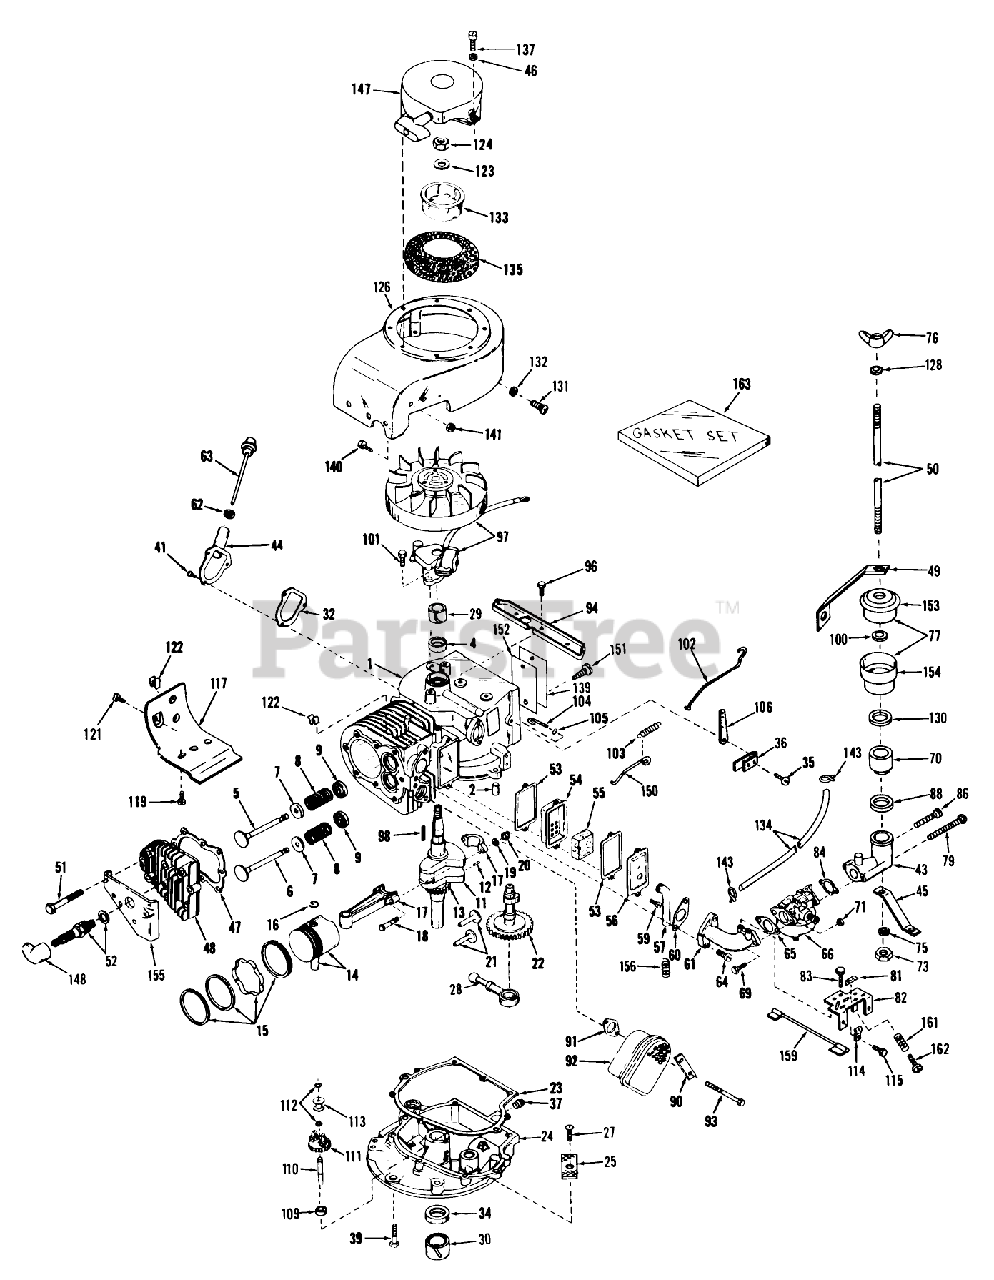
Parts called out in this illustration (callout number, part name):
1	Cylinder Assy.(Incl. Nos. 2 4)
2	Pin-Dowel
4	Seal, Oil
5	Valve, Intake (Standard)
5	Valve, Intake (1/32" oversize)(Incl. Ref. No.9)
6	Valve, Exhaust (Standard)
6	Valve, Exhaust (1/32" overs.)(Incl. Ref. No.9)
7	Cap-Spring, Valve
8	Spring-Valve
9	Cap, Lower valve spring
9	Cap, Lower Valve Spring (1/32" oversize)
10	Pin, Valve spring retaining
11	52038A RIDING MWR W
11	Crankshaft Assy 34" Whirlwind only
12	Pin, Groove
13	Gear-Crankshaft
14	Piston Pin Assy., Std., (Incl. 2 of No. 16)
14	Piston Pin Assy., .010 oversize (Incl. 2 of No. 16)
14	Piston Pin Assy., .020 oversize (Incl. 2 of No. 16)
15	Clevis Pin
15	Ring Set, Piston (.010 oversize)
15	Ring Set, Piston (.020 oversize)
17	Rod Assy., Connecting (Incl. Nos.18,19 20)
17	Rod Assy., Connecting (Incl. Nos. 18, 19 20)(Model V60-70073G only)
18	Bolt, Connecting Rod
19	Washer
21	Lifter Valve
22	Screw
23	Gasket-Cover, Cylinder
24	Flange Assy., Mounting (Incl. Nos. 25, 27, 30, 34, 37 110)
25	Screen-Oil Filter
27	Screw
28	Pump, Oil
29	Bushing, Crankshaft
30	Bushing, Crankshaft
32	Gasket, Filler tube
34	Seal-Oil
35	Screw
36	Clamp-Lever, Governor
37	Plug-Drain, Oil (SQH 1/4-18)
39	Screw (1/4-20 x 1-1/4)
41	Screw
43	Elbow, Air cleaner
44	Tube, Oil Filler
45	Brace, Cleaner elbow
46	Washer
47	Gasket-Head, Cylinder
48	CYLINDER HEAD
49	Brace Cleaner
50	Stud, Air cleaner
51	Screw
52	SPARK PLUG
53	Gasket-Breather
54	Body-Breather
55	Element-Breather
56	Cover-Valve
57	Tube-Breather
59	Screw
60	Gasket-Intake
61	Pipe, Intake
62	Gasket
63	Dipstick, Oil (Incl. No. 62)
64	Screw (T-30, 5/16-18x1-3/32)
65	Gasket
66	Carburetor
70	Spacer, Cleaner
71	Nut and Lock Washer (1/4-28)
75	Lockwasher, Split
76	Nut-Wing
77	Cleaner Assy., Oil Bath Air (Incl. Nos.100,128,130,153 154)
79	Screw
81	Decal
82	Control Assy., Speed
83	Screw (10-24 x 9/16)
84	Gasket
86	KIT - SEAL WIPER
88	Gasket, Spacer
90	62513 SNWTHWR W/284
91	Gasket Exhaust
92	Muffler
93	Screw (1/4-20x19/32)
94	Bracket, Blower Housing (Incl. Nos. 131)
96	Screw (1/4-20x19/32)
97	Magneto
98	Key, Flywheel
100	O Ring
101	Screw
102	Link Governor
103	Spring Governor
104	Rod, Governor (Incl. Nos. 146)
105	Washer-Flat
106	Lever-Governor
109	Spacer
110	Shaft, Governor
111	Governor Gear ASM
112	Ring-Retaining
113	Spool-Governor
114	Conduit
115	Screw (10-32 x 3/8)
117	Emnsion, Blower Housing
119	Screw
121	Screw
122	51004 GIL ROTARY TI
123	Washer
126	Housing, Blower
128	Washer
130	1565F GIL TILLER.AD
131	Screw
132	Lockwasher
133	Cup-Starter
134	Line-Fuel
135	Screen, Air
137	Screw
139	480B GIL SNWTHWR O/
140	Screw
141	Nut-Jam (5/16-24)
143	Clamp-Line, Fuel
147	Starter, Rewind
148	Cover-Spark Plug
150	Link, Governor spring
151	Stud
152	IDENTIFICATION PLATE
153	Cover, Oil bath cleaner
154	Bowl, Oil Bath Cleaner
155	Cover, Cylinder head
156	Spring, Coil
159	Wire, Ground
161	Spring-Compression
162	Screw
163	Gasket Set
